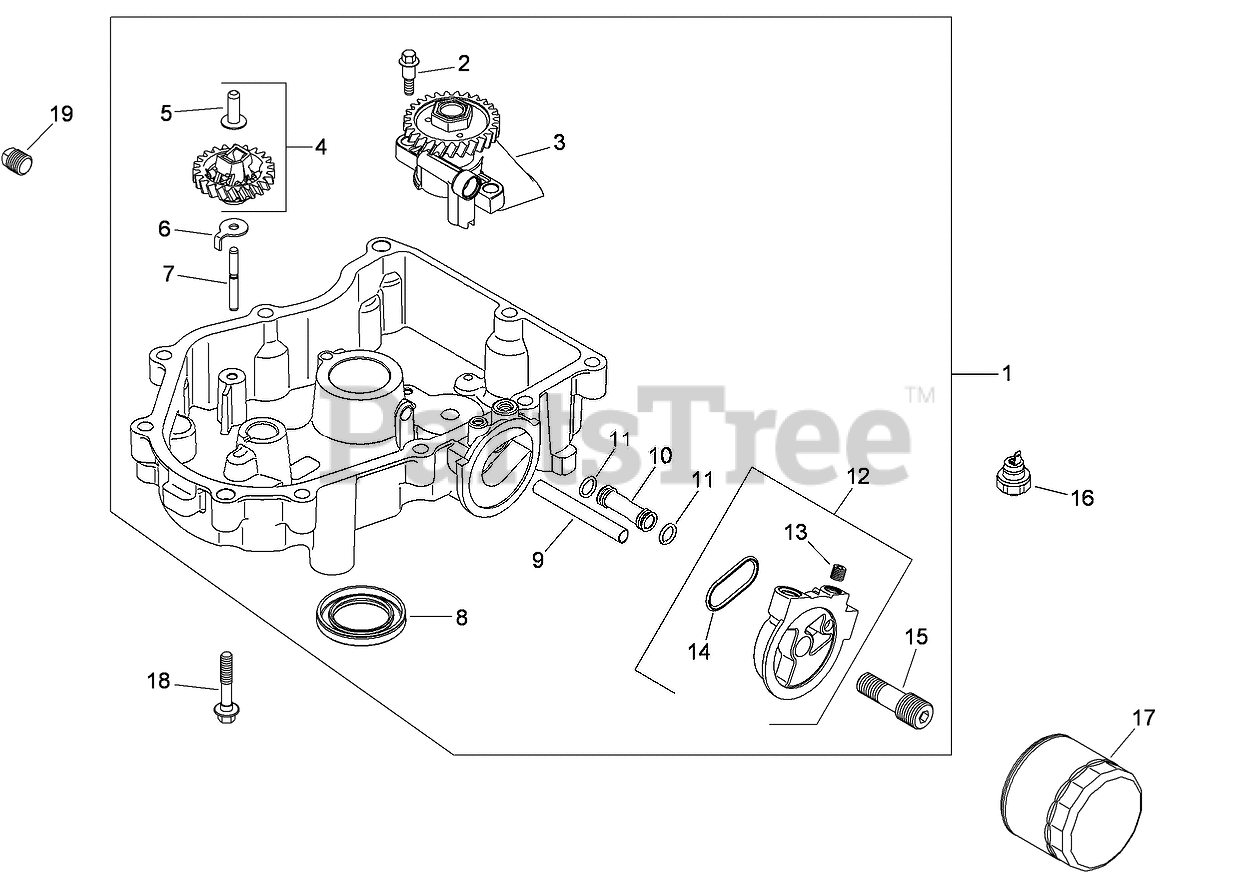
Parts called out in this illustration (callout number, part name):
1	OIL PAN ASM (INCLUDES REF 2, 5-15)
2	SCREW-SHOULDER, THD FRM (M6x1.0x26.5)
3	OIL PUMP ASM
4	GOVERNOR GEAR W/PIN KIT (INCLUDES REF 5)
5	PIN-REGULATING, GOVERNOR
6	TAB-LOCKING
7	SHAFT-GEAR, GOVERNOR
8	SEAL-OIL
9	TUBE-FEED, OIL (FILTER TO PAN)
10	TUBE-FEED, OIL (PAN TO FILTER)
11	O-RING (OIL PICK-UP)
12	ADAPTER OIL FILTER KIT (INCLUDES REF 13, 14)
13	PLUG-PIPE, COUNTERSUNK (1/8)
14	O-RING (OIL FILTER ADAPTER)
15	NIPPLE-FILTER, OIL
16	SWITCH-PRESSURE, OIL
17	FILTER-OIL
18	SCREW-FLANGE (M8X1.25X45)
19	PLUG-PIPE, SQ HD (3/8)
